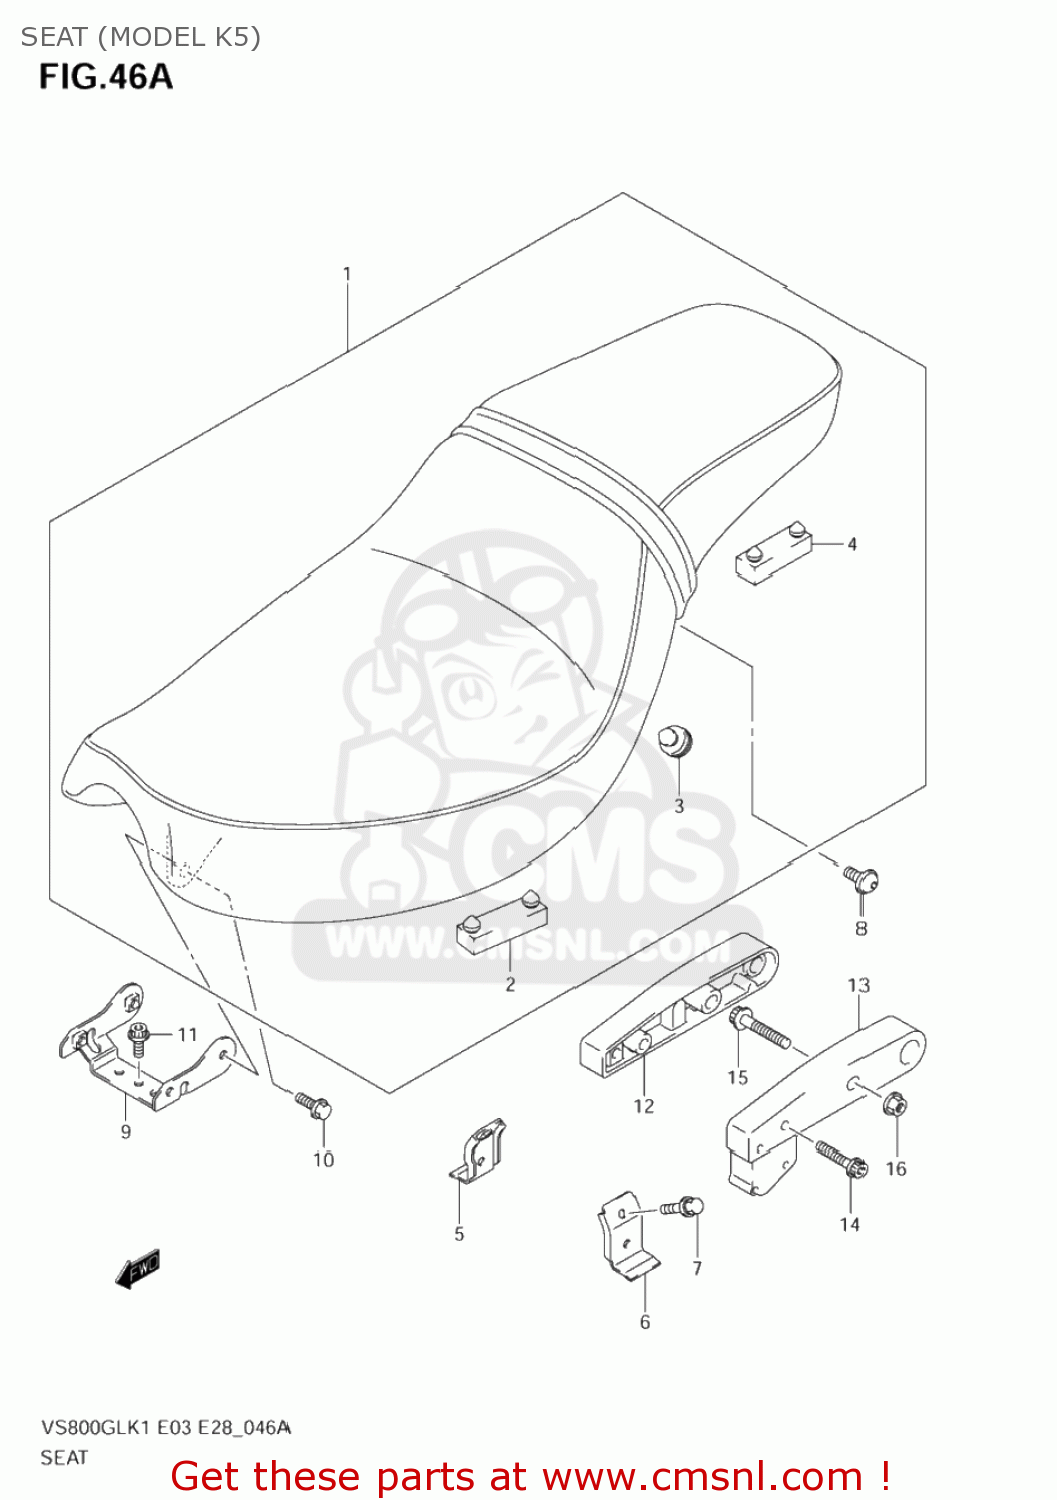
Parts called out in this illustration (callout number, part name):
1	SEAT ASSY
2	CUSHION,SEAT
3	CUSHION(11.5X22X20)
4	CUSHION
5	BRACKET,SEAT CTR,R
6	BRACKET,SEAT CTR,L
7	BOLT
8	SCREW(6X12)
9	BRACKET,SEAT FR
10	BOLT(6X16)
11	BOLT MAGNETO S
12	HANDLE,PILLION RIDER,R
13	HANDLE,PILLION RIDER,L
14	BOLT
15	BOLT
16	NUT
